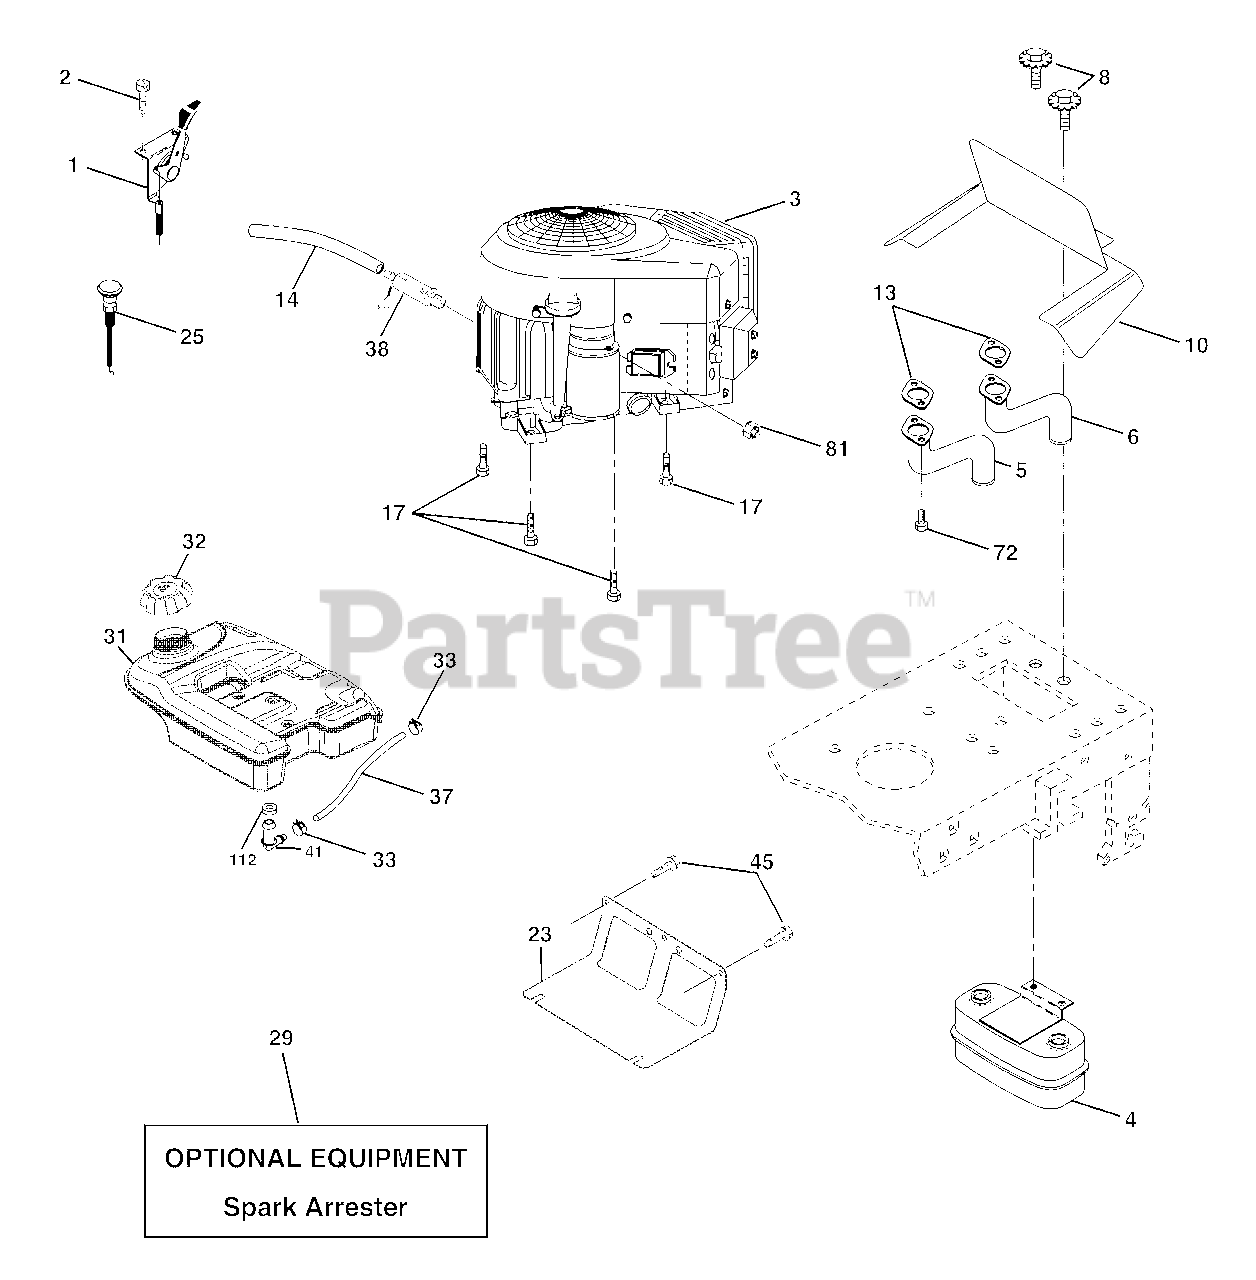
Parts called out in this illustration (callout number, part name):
1	Control Throttle
2	Screw Hw Hd Hi-Lo #13-16 x 3/4
4	Muffler Asm Twin Lo-Tone
5	Pipe Exhaust LH Intek
6	Pipe Exhaust RH Intek
8	Bolt 5/16-18 unc x 3/4 w/Sems
10	Shield Browning Intek II
13	Muffler Gasket
14	Tube Drain Oil Easy
17	Screw Thdrol 3/8-16 x 1-1/2
23	Shield Heat
25	Choke Control
29	Kit Spark Arrestor (Flat Scrn)
31	Tank Fuel 4.0 Rear
32	Cap Asm Fuel
33	Clamp Hose Black
37	Line Fuel
38	Plug Drain Oil
41	Stem Tank Fuel
45	Screw Hexwsh Thdr 3/8-16 x 3/4
72	Screw Socket Head 5/16-18 x 1
81	Nut Keps Hex 1/4-20 unc
112	Bushing
